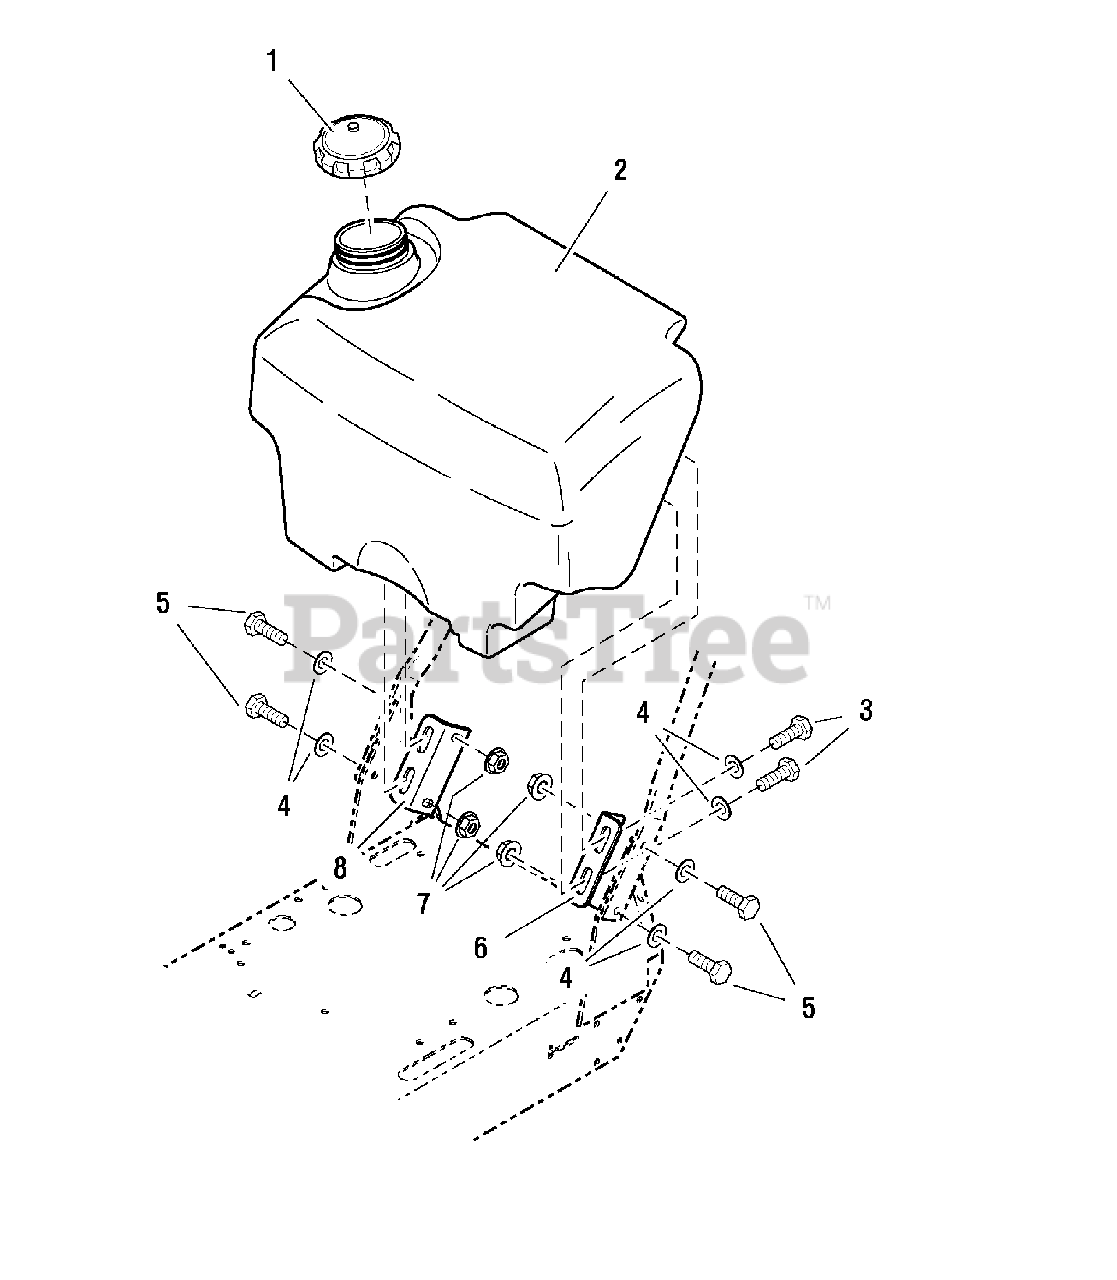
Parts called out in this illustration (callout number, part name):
1	FUEL TANK CAP
3	CAPSCREW, Hex Head, 3/8-16 x 3/4
4	WASHER, 3/8
5	CAPSCREW, Hex Head, 3/8-16 x 1-1/4
6	FUEL TANK MOUNT - LH
7	NUT, Hex Serrated Flange, 3/8-16
8	FUEL TANK MOUNT - RH
